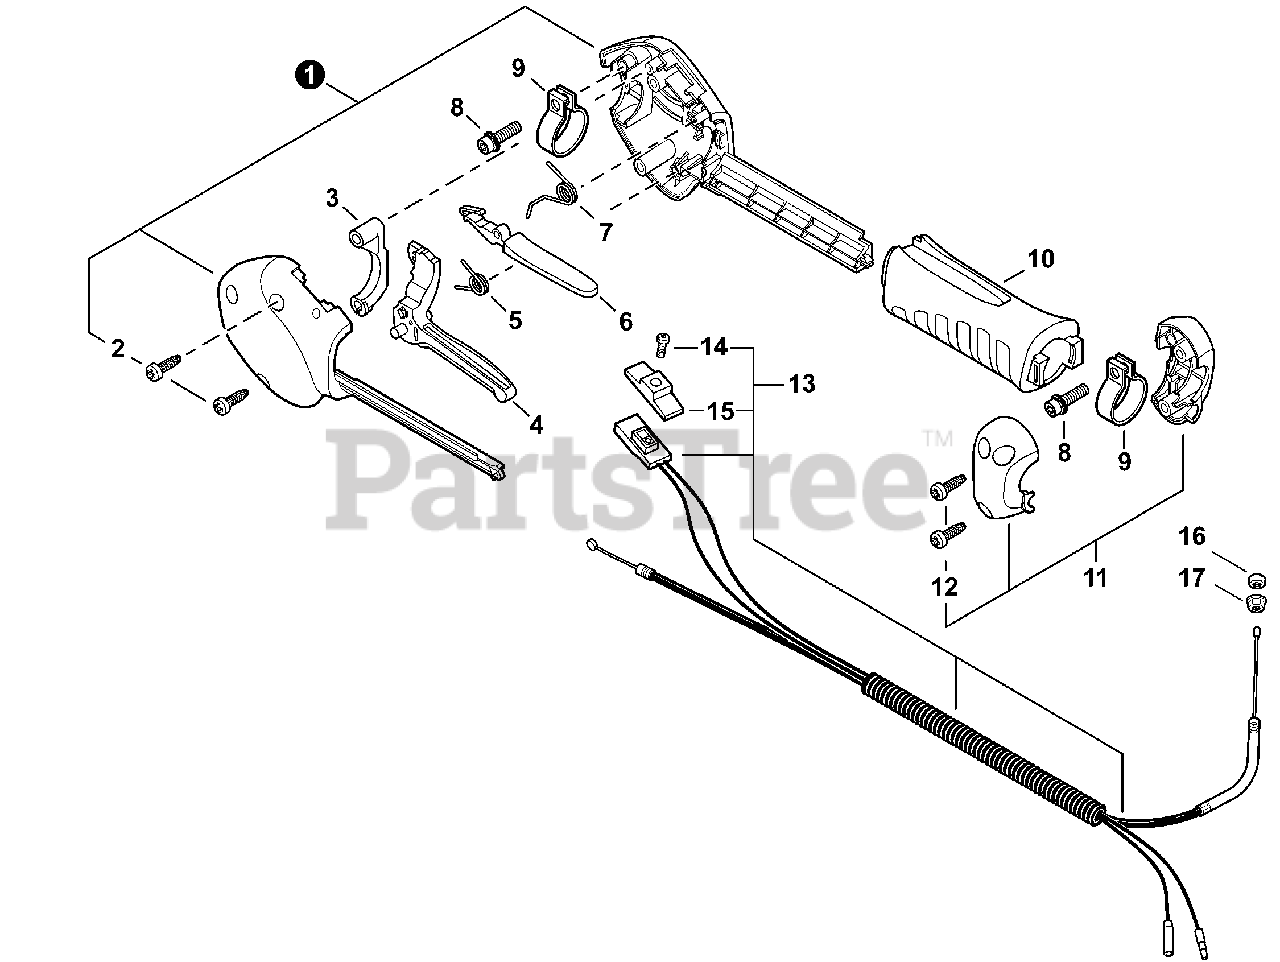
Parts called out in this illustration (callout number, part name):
1	HANDLE KIT, CONTROL
2	BOLT, TORX 4×20
3	LOCKOUT, THROTTLE
4	TRIGGER, THROTTLE
5	SPRING, TORSION
6	LEVER, THROTTLE LOCKOUT
7	SPRING, TORSION
8	BOLT, TORX 5×20
10	GRIP, HANDLE
11	FIXTURE SET, HANDLE
12	BOLT, TORX 4×20
13	CABLE ASSY, CONTROL
14	SCREW 3×10
15	KNOB, SWITCH - ORANGE
17	NUT, FLANGE 6
